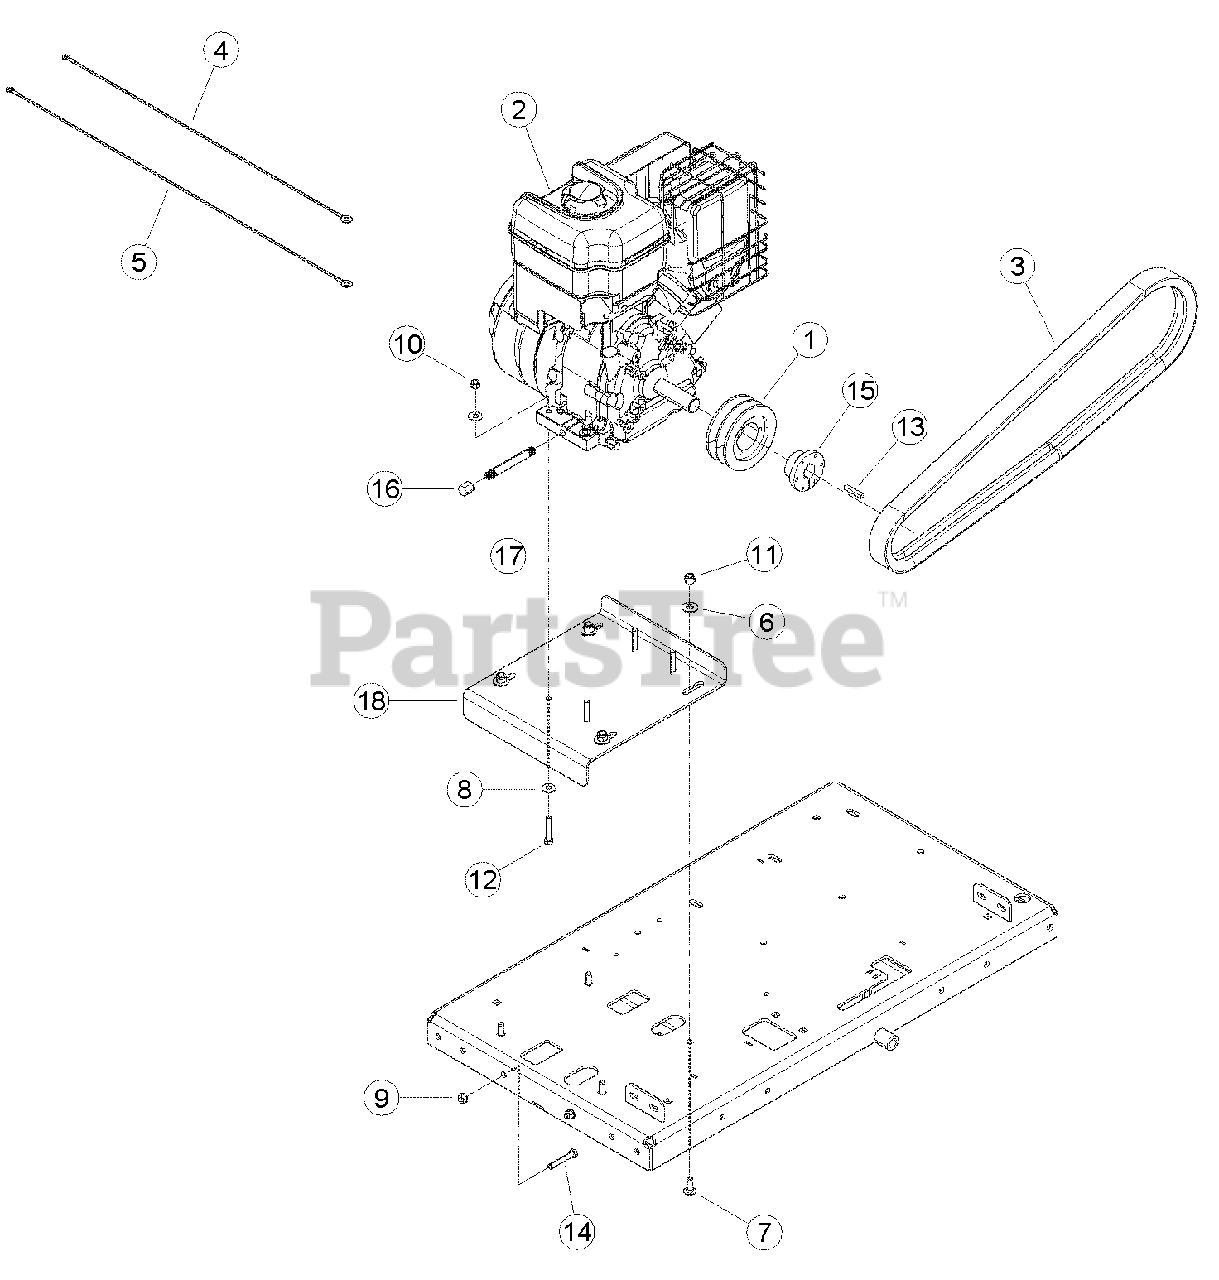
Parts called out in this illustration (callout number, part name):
1	SHEAVE, 2B4.4 SH, QD
2	ENGINE, 342CC ELEC B+S HORIZONTAL (FOR SERVICE SEE ENGINE OWNER'S MANUAL OR YOUR NEAREST AUTHORIZED BRIGGS & STRATTON ENGINE DEALER)
3	BELT, 2RB61 ARAMID
4	WIRE, 25" NEG (R / INSUL R)
5	WIRE, 30" POS (INSUL RINGS)
6	WASHER, 3/8 FLAT ZP
7	BOLT, 3/8 X 1 CRG GR5 NC ZP
8	WASHER, 5/16 FLAT ZP
9	NUT, 5/16 SERR FLANGE NC ZP
10	NUT, 5/16 NE NYLOCK ZP
11	NUT, 3/8 NE NYLOCK ZP
12	BOLT, 5/16-18 X 1-3/4 HEX HD GR5 ZP
13	KEY, 1/4 SQUARE X 1-1/2 LONG PLAIN
14	BOLT, 5/16 X 3 NC FULL THD
15	BUSHING, SH 1"
16	PIPE CAP, 1/4" GALV.,HEX HEAD
17	PIPE NIPPLE, 1/4 X 4" GALVANIZED
18	PLATE, 12 HP B+S ENGINE
